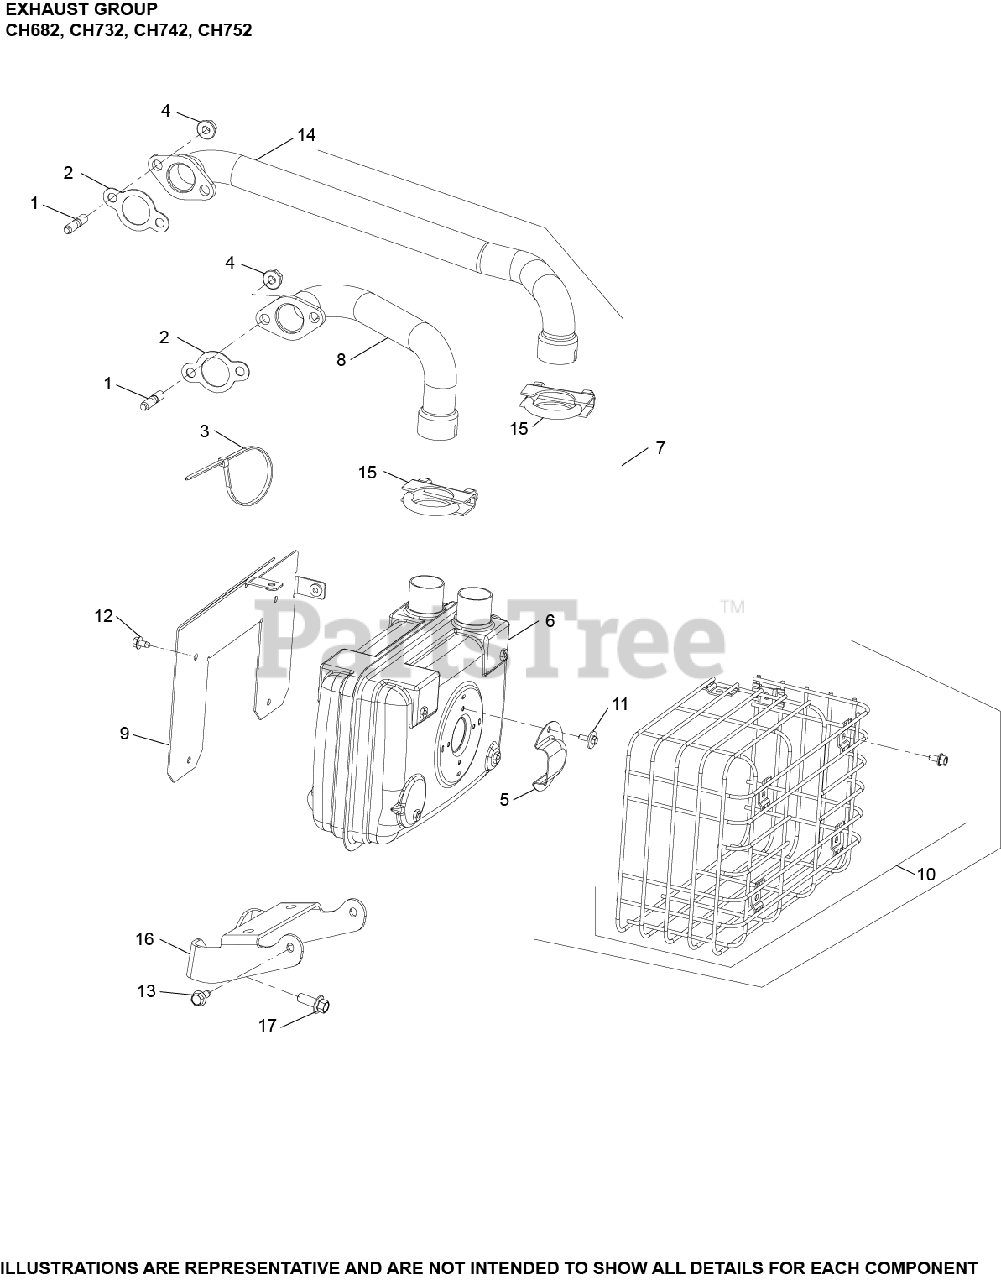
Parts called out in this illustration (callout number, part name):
2	GASKET, EXHAUST
4	NUT, FLG M8X1.25
5	DEFLECTOR, EXHAUST
6	MUFFLER, STARTER SIDE/STRAIGHT USE 24 068 156-S
7	MUFFLER KIT, STARTER SIDE/STRAIGHT
8	MANIFOLD, EXHAUST
9	HEAT SHIELD, MUFFLER USE 24 314 58-S
10	KIT, WIRE GUARD
11	SCREW, SEMS DRILL #8-18X1/2"
12	SCREW, THREAD FORMING
13	SCREW, THREAD FORMING
15	CLAMP, MUFFLER
16	BRACKET, MUFFLER
17	SCREW, FLG M8X1.25X20
